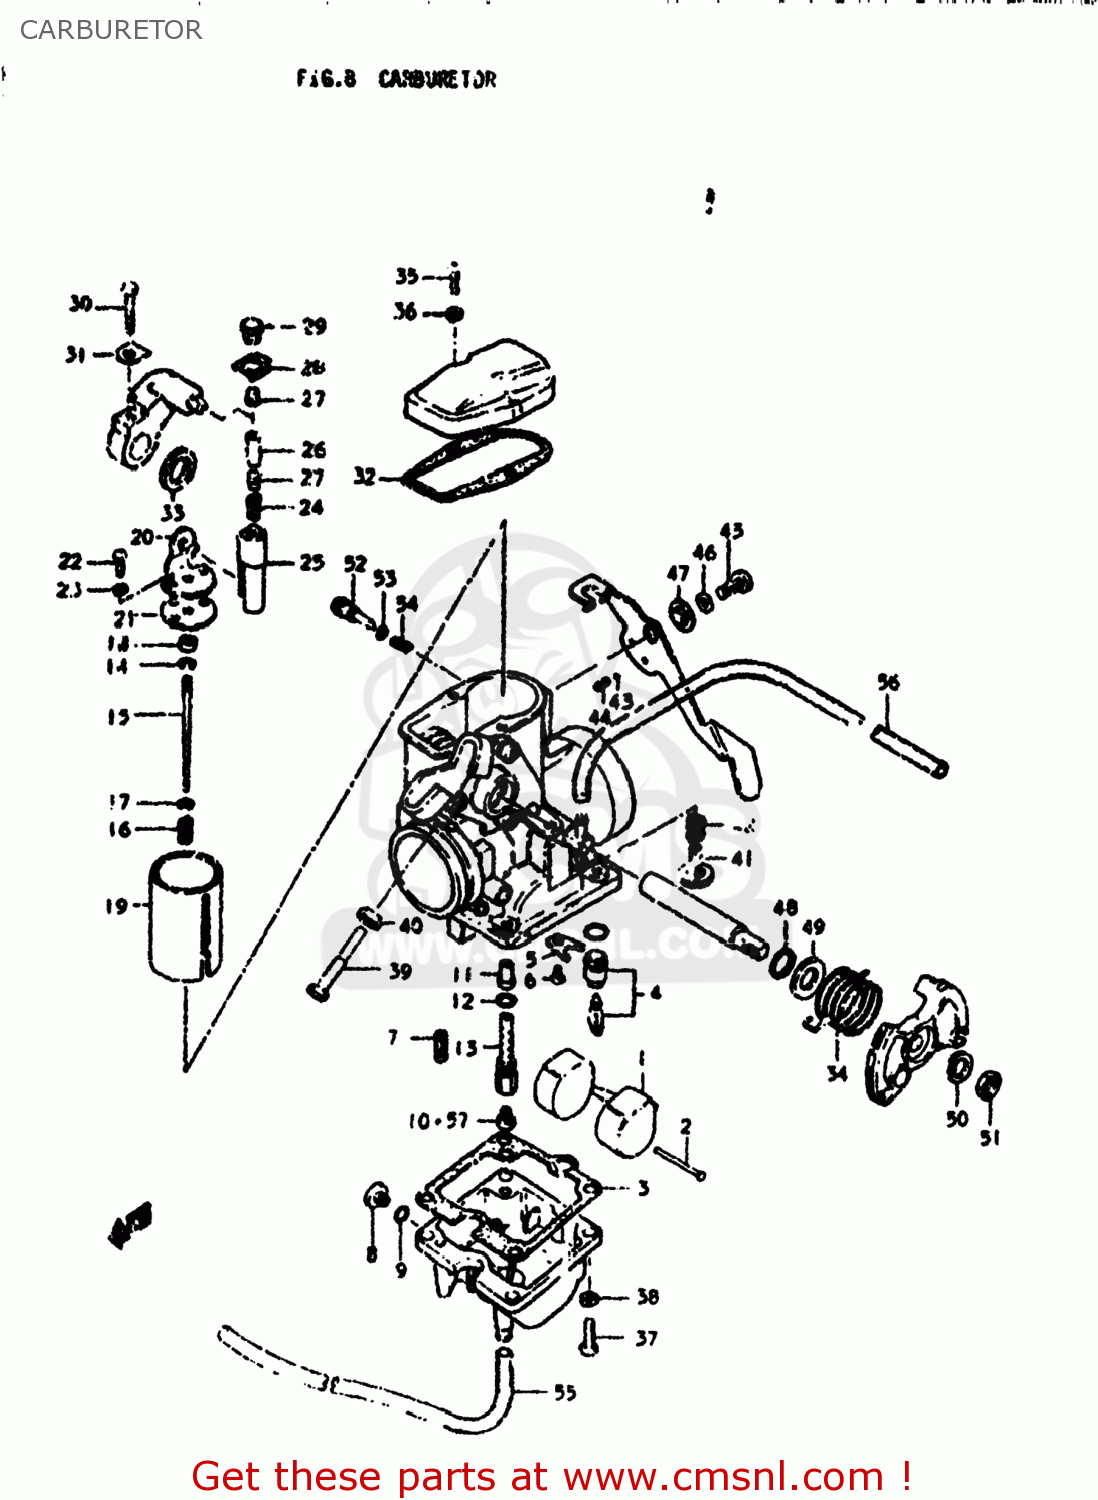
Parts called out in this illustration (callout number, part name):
1	FLOAT
2	PIN,FLOAT
3	GASKET,FLOAT CAHMBER (NAS)
4	VALVE ASSY,NEEDLE
5	PLATE
6	SCREW
7	JET,PILOT(25)
8	SCREW
9	O RING
10	JET,MAIN(125)
11	HOLDER,JET
12	O RING
13	JET,NEEDLE
14	CLIP
15	NEEDLE JET
16	SPRING
17	WASHER,JET NEEDLE
18	RING
19	VALVE,THROTTLE
20	BRACKET,CARBURETOR
21	PLATE,THROTTLE VALVE
22	SCREW
23	LOCK WASHER
24	SPRING,CARBURETOR
25	LEVER ASSEMBLY
26	SPRING
27	PIN,CARBURETOR
28	PLATE,CARBURETOR
29	SCREW
30	BOLT
31	RING
32	GASKET,TOP (NAS)
33	RING
34	RING
35	SCREW
36	LOCK WASHER
37	SCREW
38	LOCK WASHER
39	SCREW
40	NUT
41	ADJUSTER
42	SPRING,THROTTLE SCREW
43	BALL,CARBURETOR
44	SPRING
45	SCREW 6X12
46	LOCK WASHER
47	RING,CARBURETOR STARTER
48	SEAL
49	RING
50	WASHER
51	NUT
52	SCREW,PILOT AIR ADJUSTING
53	O RING
54	SPRING
55	HOSE
56	HOSE
